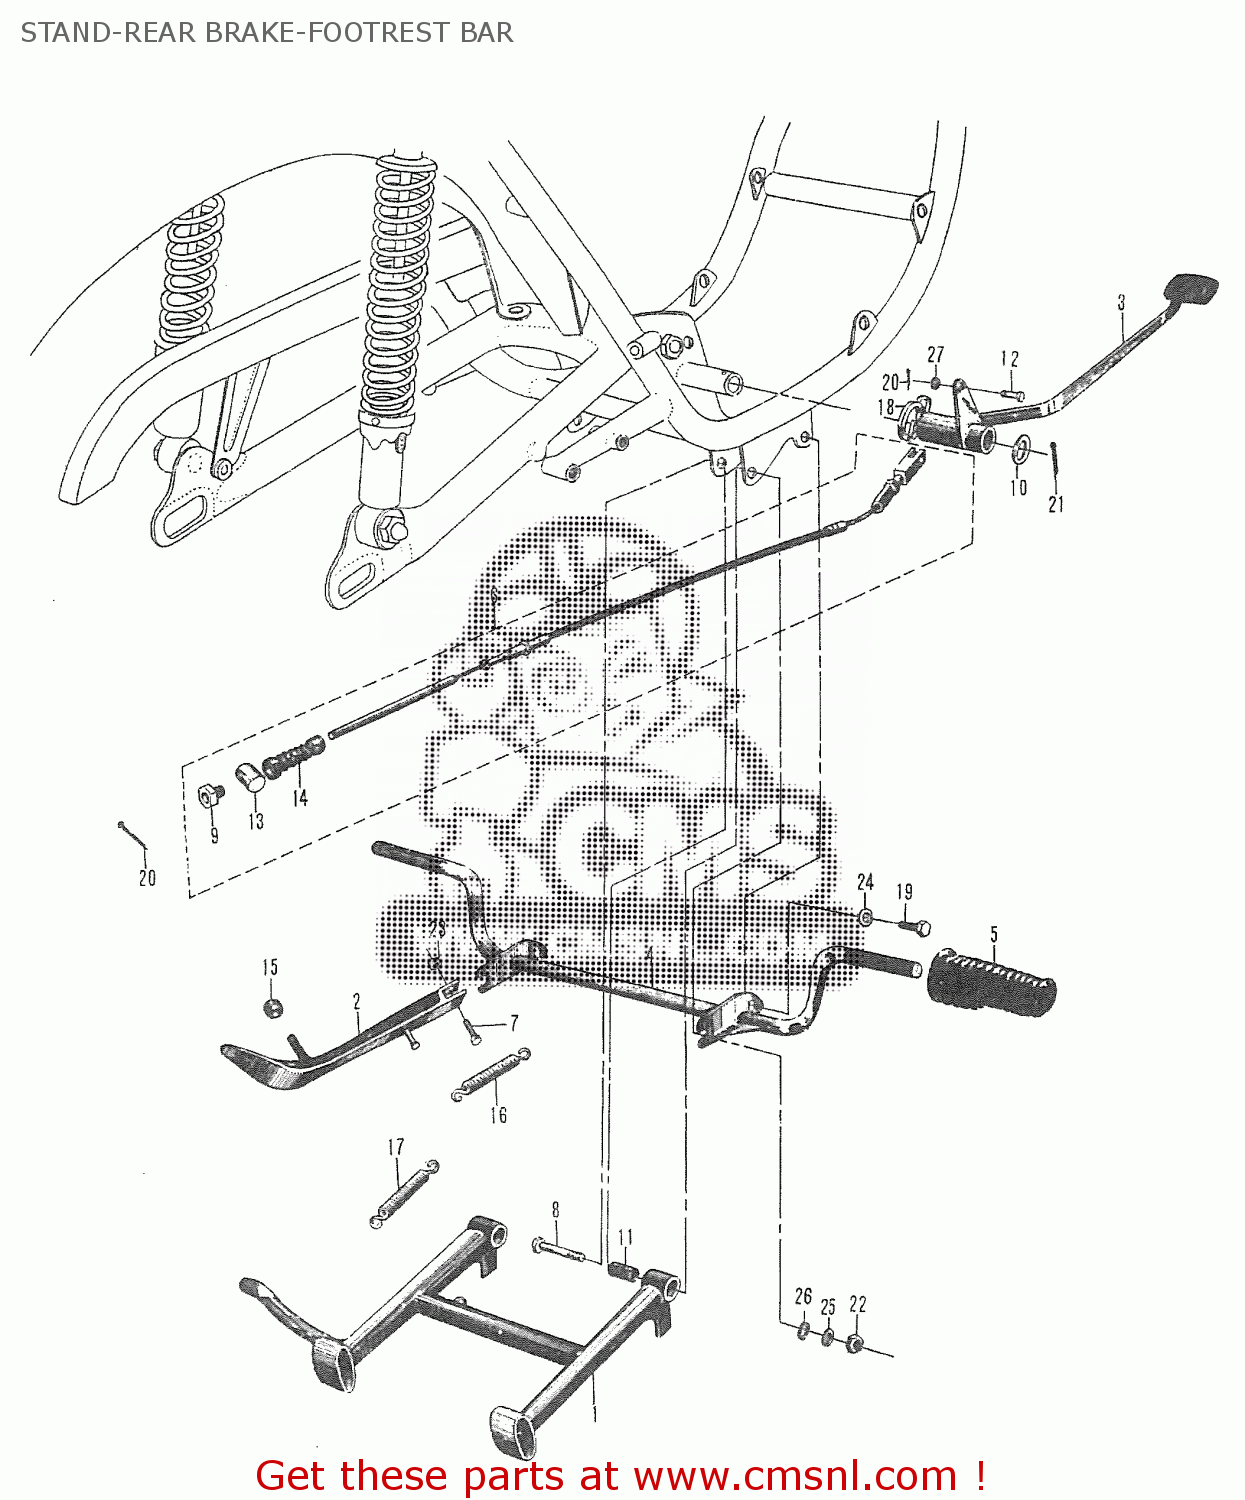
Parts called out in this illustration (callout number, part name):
1	CENTER STAND
2	STAND,PROP
3	BRAKE PEDAL
4	FOOTREST BAR
5	RUBBER,FR FOOTREST
6	CABLE ASSY,RR BRAKE
7	BOLT
8	CENTER STAND BOLT
9	NUT
10	WASHER
11	SPACER(10.5X16X30)
12	PIN(L:17.5)
13	PIN
14	SEAL,DUST
15	CUSHION
16	SPRING
17	SPRING
18	SPRING
19	SMALL HEAD HEXAGON BOLT
20	COTTER PIN
21	COTTER PIN
22	SMALL HEXAGON NUT
23	SMALL HEXAGON NUT
24	LOCK WASHER
25	LOCK WASHER
26	SMALL FLAT WASHER
27	FLAT WASHER
